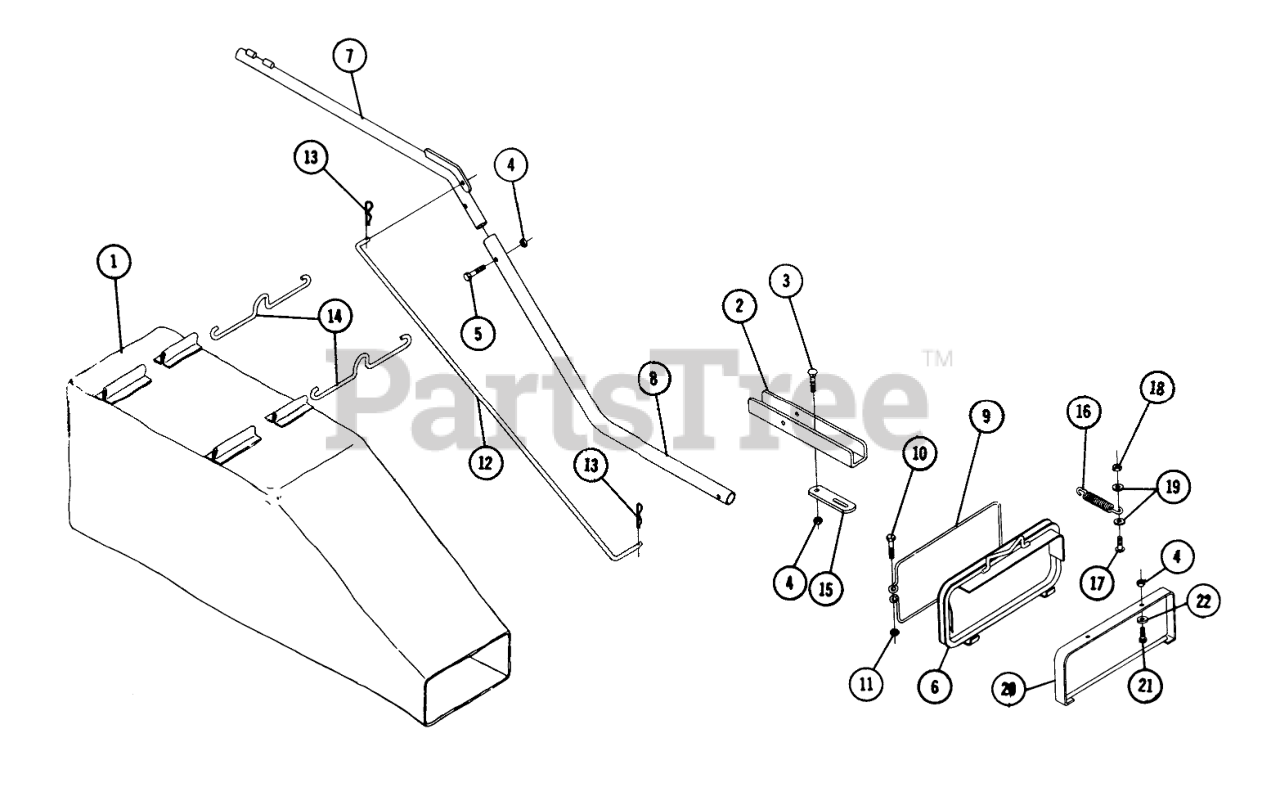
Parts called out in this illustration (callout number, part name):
2	Channel
3	Bolt-Car. 5/16-18 x 1
4	Nut 5/16-18
5	Bolt 5/16-18 x 11/4
6	Frame
7	Upper Arm
8	Arm-lower
9	Hoop-Wire
10	Bolt 1/4 20 x 1 1/4
11	Nut-Nylok
12	Link
13	Hairpin
14	Hook
15	Link
16	SPRING R
17	Bolt 3/8-16 x 1 Pan Hd.
18	3/8-16 E.S.
19	Washer
20	Strap Assembly
21	Bolt, 5/16-18 x 3/4
22	Spacer
